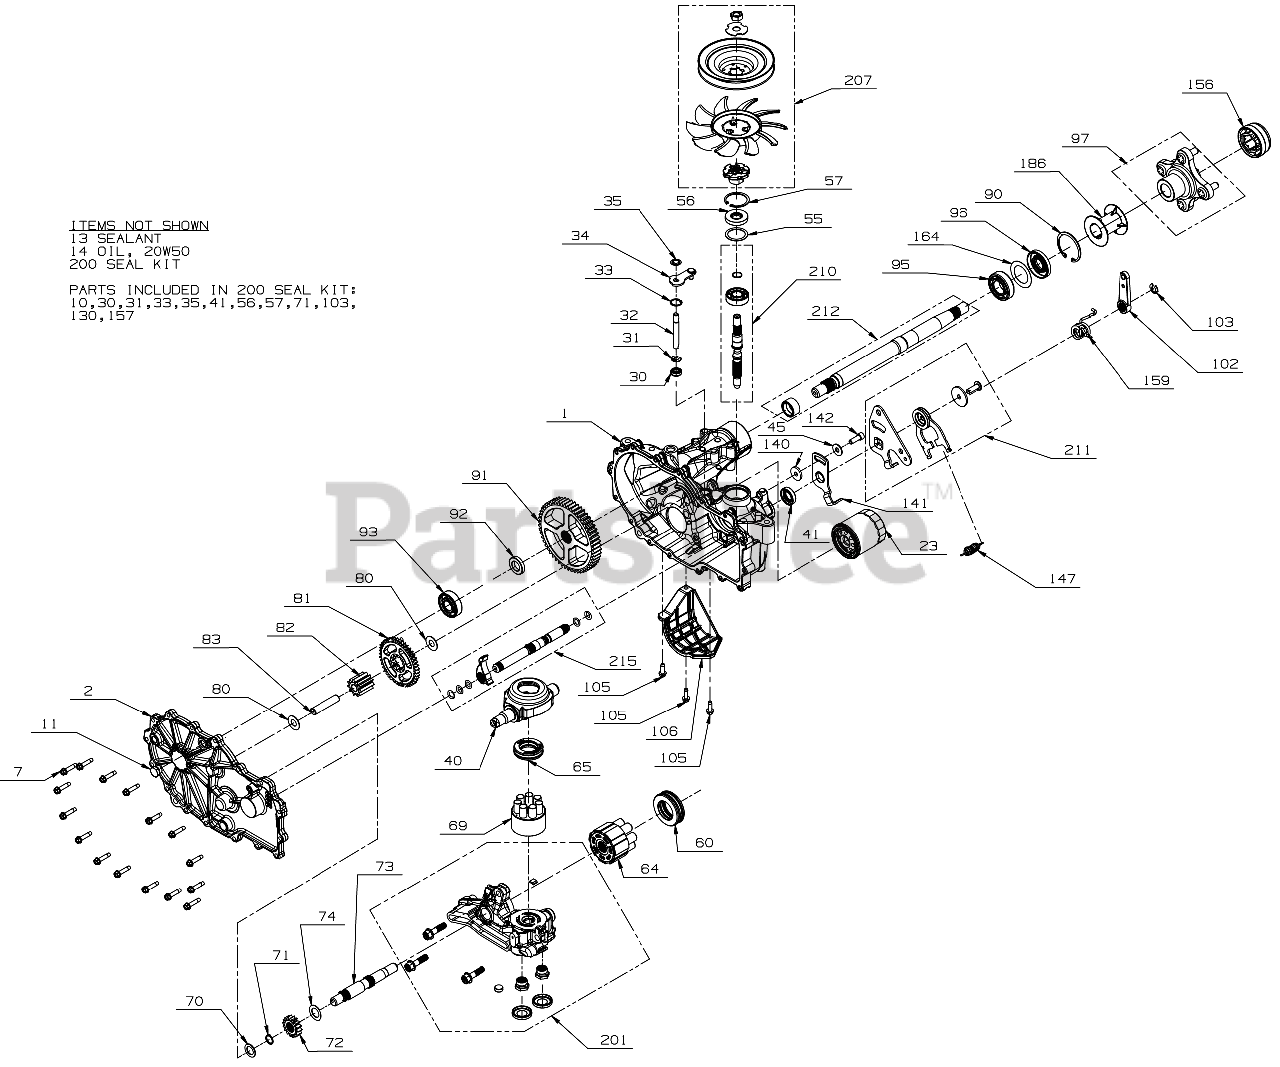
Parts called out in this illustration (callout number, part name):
1	HOUSING KIT-MAIN
2	COVER KIT-SIDE (LH)
7	SCREW-WASHER HEAD
11	VENT PLUG
13	SEALANT-HOUSING
23	OIL FILTER
30	SEAL-LIP .375
31	RETAINING RING
32	BYPASS RODS
33	RETAINING RING
34	ARM-BYPASS
35	RETAINING RING
40	SWASHPLATE-TRUNNION
45	FLAT WASHER
55	WASHER 1.23X1.56X
57	RETAINING RING
60	THRUST BEARING
64	CYLINDER BLOCK ASSEMBLY
65	THRUST BEARING
69	BLOCK KIT-7 PISTON
70	FLAT WASHER
71	RETAINING RING
72	GEAR-16 T
73	MOTOR SHAFT
74	MOTOR SHAFT WASHER
81	GEAR-43 T
82	GEAR-11 T
83	PIN-JACKSHAFT
90	RETAINING RING
91	GEAR-54 T
92	SPACER .75X1.32X.257
93	BALL BEARING
95	BALL BEARING
97	HUB-4 BOLT WHEEL
102	BRAKE LEVER
103	RETAINING RING
106	GUARD-FILTER (LH)
140	SPACER .32 x 1.005 x .179
141	ARM-NEUTRAL (LH)
142	SCREWS KIT-RTN
147	EXTENSION SPRING
156	COVER-NUT
159	TORSION SPRING CW
186	TUBE-AXLE 2.03
200	SEAL KIT
201	SECTION KIT-CENTER
207	KIT-FAN & PULLEY
207	FAN-7.0 (10 BLADE)
207	HUB-PULLEY
207	WASHER-SLOTTED
209	PULLER KIT-HUB
210	SHAFT KIT-INPUT
211	RETURN KIT-NEUTRAL (LH) ZT2800 RZT
212	SHAFT KIT-AXLE
215	OUTPUT SHAFT KIT (LH)
